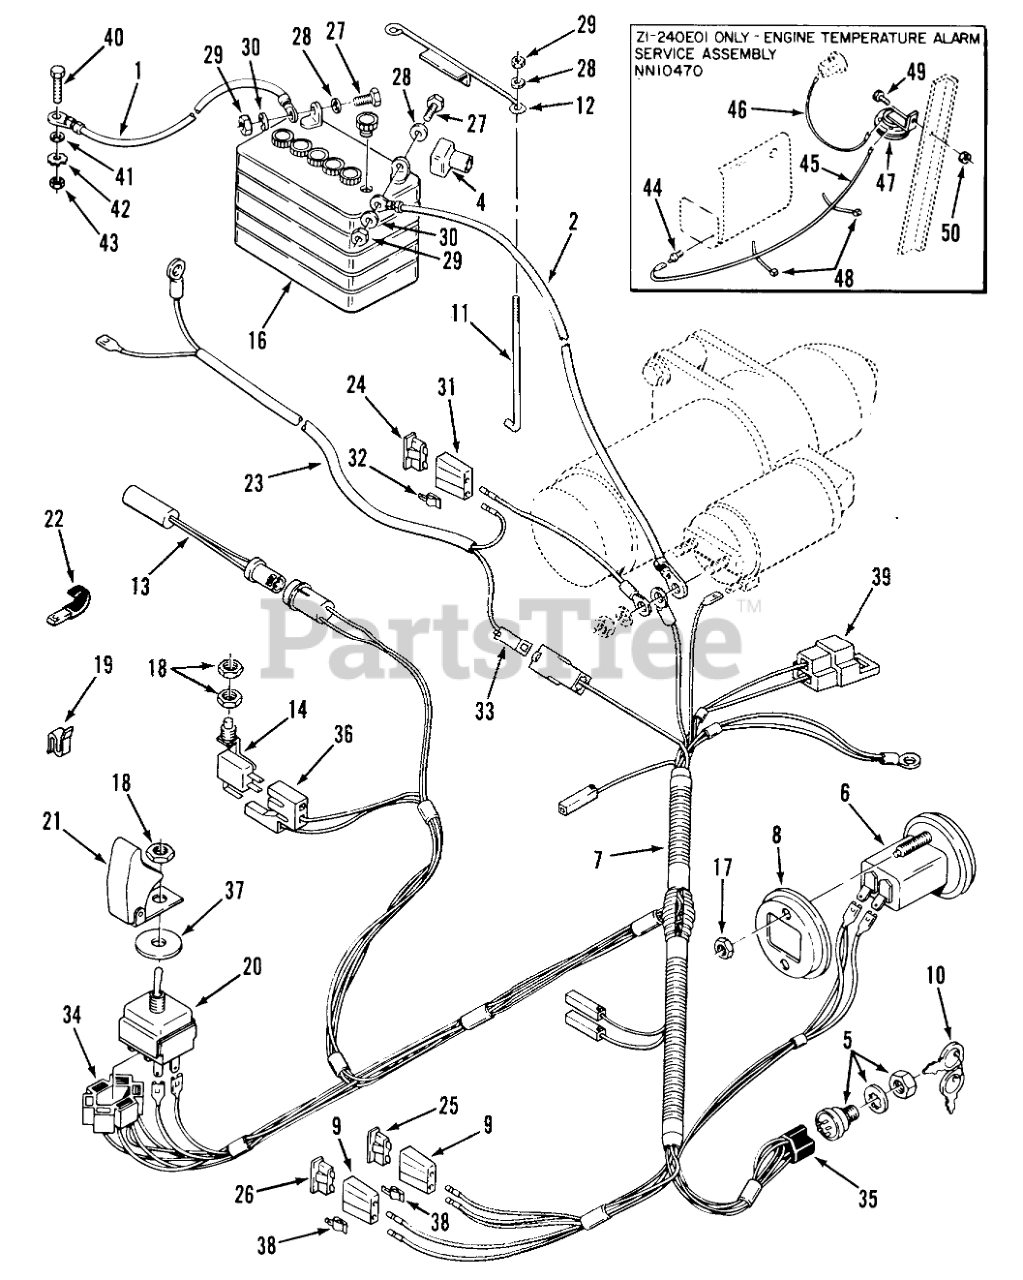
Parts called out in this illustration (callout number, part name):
1	WIRE -BLACK
2	ASS'Y-WIRE BATTERY
4	Boot
5	Ignition Switch (includes 101884 Nut)
6	Hourmeter (includes item 8)
7	Wiring Harness
8	BRKT-GAUGE MOUNTING
9	AUTO-FUSEBLOCK TERM
10	KEY PADDED
12	HOLDDOWN-BATTERY
13	ASS'Y-SWITCH HARNESS
14	Seat Switch
16	Battery
17	Hex Nut
18	NUT-HEX, SPECIAL
19	CLIP-CABLE
20	SWITCH CLUTCH
21	COVER-PTO SWITCH
22	CLIP
23	ENG WIRING HARNESS
24	FUSE-30 AMP
25	FUSE-BLADE, 7.5 AMP
26	FUSE-BLADE, 15 AMP
27	Bolt
29	Nut
30	Washer
31	CONNECTOR CAP
32	CONNECTOR CLIP
33	MALE CONNECTOR
34	CONNECTOR 5 WAY
35	CONNECTOR-5 WAY-SERV
36	CONNECTOR BODY
37	WASHER
39	CONNECTOR BODY
40	Bolt
42	LCKWSHR 1/4 INT TTH
43	Nut
44	HIGH TEMPERATURE
48	PLASTIC TIE
49	BOLT
50	NUT
